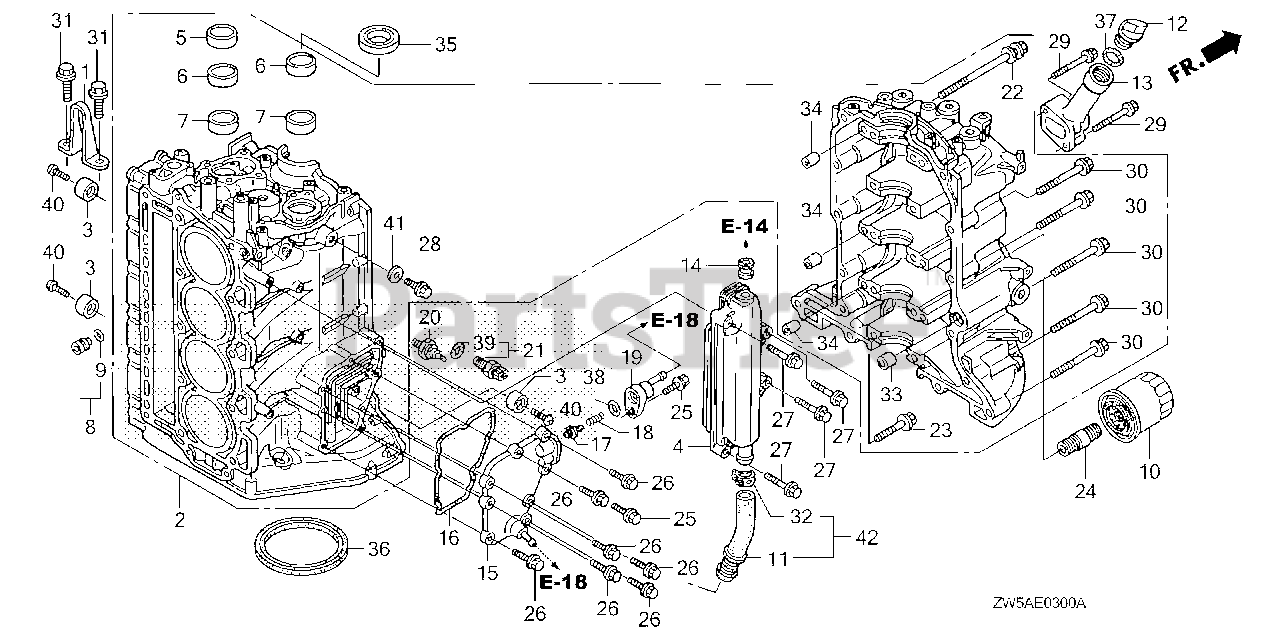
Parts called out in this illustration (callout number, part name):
1	HANGER, ENGINE
2	BLOCK ASSY., CYLINDER *NH8* (DARK GRAY)
3	METAL, ANODE
4	CHAMBER, PCV
5	METAL, BALANCER SHAFT (NO.1) (DAIDO)
6	METAL, BALANCER SHAFT (NO.2) (DAIDO)
7	METAL, BALANCER SHAFT (NO.3) (DAIDO)
8	ORIFICE ASSY., OIL CONTROL
9	O-RING (10.8X2.4) (ARAI)
10	FILTER, OIL (FILTECH TOYO ROKI) (SOLD IN MULTIPLES OF 30)
10	FILTER, OIL (FILTECH TOYO ROKI) (SOLD INDIVIDUALLY)
10	FILTER, OIL (TOYO ROKI) (SOLD INDIVIDUALLY)
11	TUBE, OIL
12	CAP, OIL (YELLOW)
13	EXTENSION, OIL FILLER
14	GROMMET, PCV VALVE
15	COVER, OIL WATER JACKET *NH8* (DARK GRAY)
16	GASKET, OIL WATER JACKET COVER
17	VALVE, OIL WATER JACKET PRESSURE
18	SPRING, OIL WATER JACKET PRESSURE VALVE
19	HOLDER, OIL WATER JACKET PRESSURE VALVE
20	SWITCH ASSY., OIL PRESSURE
21	SENSOR ASSY., WATER TEMPERATURE
22	BOLT-WASHER (11X131)
23	BOLT, FLANGE (10X40)
24	HOLDER, OIL FILTER
25	BOLT, FLANGE (6X25)
26	BOLT, FLANGE (6X20)
27	BOLT, FLANGE (6X35)
28	BOLT, DRAIN PLUG (12MM)
29	BOLT, FLANGE (6X40)
30	BOLT, FLANGE (10X55)
31	BOLT, FLANGE (12X30)
32	CLAMP, TUBE (D29)
33	PIN, DOWEL (18X22)
34	PIN, DOWEL (13X20)
35	OIL SEAL (40X52X7)
36	OIL SEAL (98X80X10) (NOK)
37	O-RING (26X2.7)
38	O-RING (16.5X2.5)
39	O-RING (9.5X1.5) (HONDA KIKAKI)
40	SCREW, PAN (6X18)
41	WASHER, DRAIN PLUG (12MM)
42	TUBE SET, OIL
